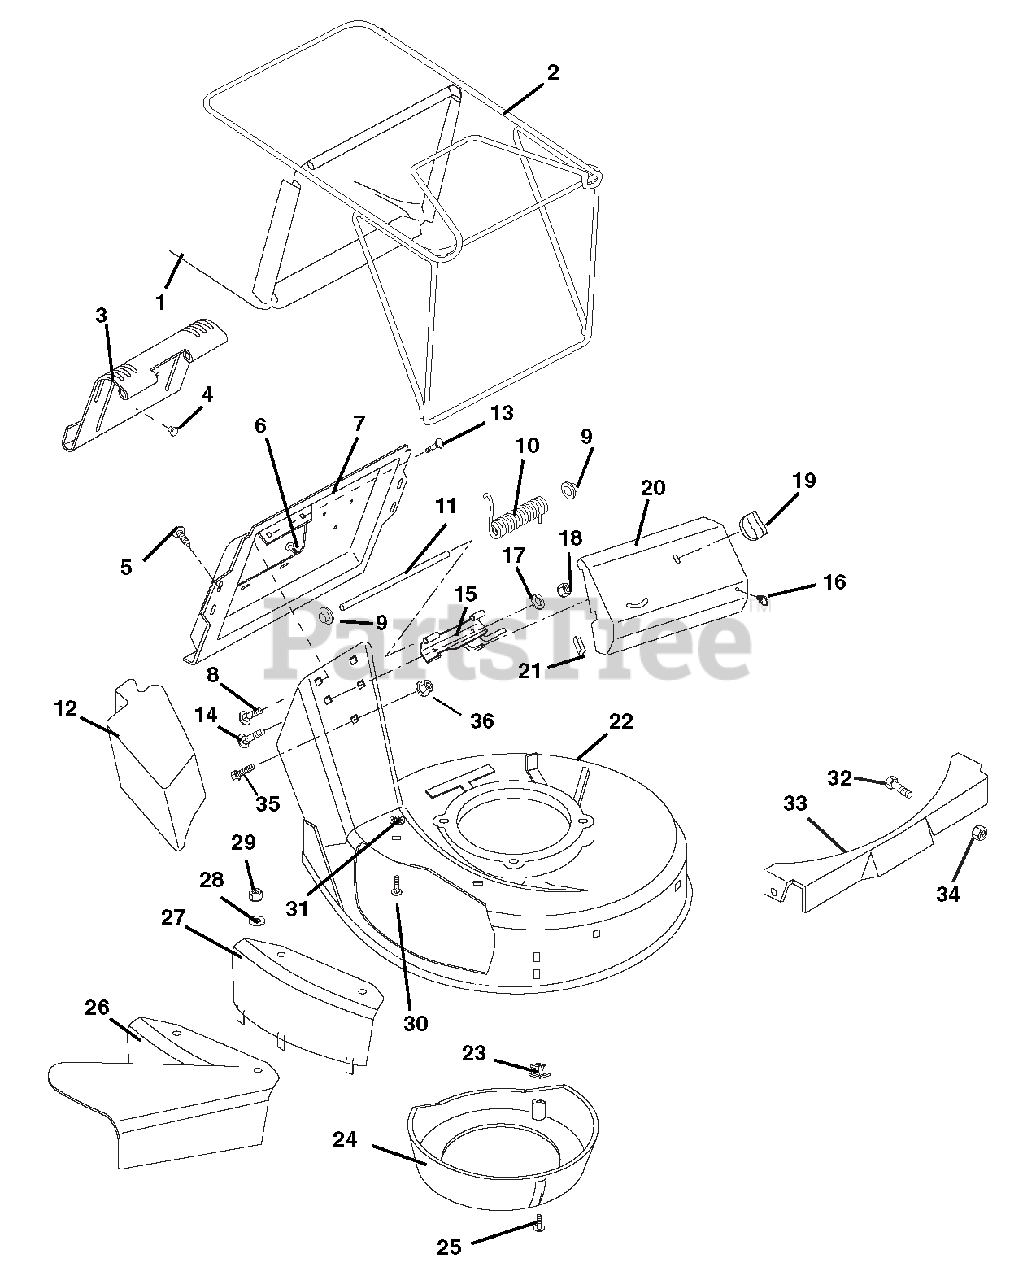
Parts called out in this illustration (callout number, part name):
1	BAG, CONSUMER BLACK 15 OZ/YD2
2	FRAME, WBLM BAGGER
3	CATCHER PLATE DOOR
4	BUTTON BUMPER
5	@SCR-TAP 12-24X.50 HWH TR YWZC
6	SCR-TAP 10-24X.375 TORX PHD YZ
7	CATCHER PLATE
8	@BLT-RHDSSQNK .25-20X.38 G2YZ
9	PUSH NUT, .25
10	SG-TORS .120X.68X3.09
11	DOOR PIN
12	MULCH MASTER MULCHER ACCESSORY
13	@NUT-SPNLK-FLG .25-20 YWZC
14	@BLT-RDHDSQNK .25-20X.75 G5YZ
15	HINGE BASE WELDEMENT
16	SNAP-IN CLIP
17	WSHR-LK .250X.077 HVY YWZC
18	@NUT-HEX .25-20 YWZC
19	WING - NUT
20	COVER, DRIVE
20	COVER, LM DRIVE
21	TRIM BUMPER
22	MOWER PAN HEAD W/SFTYDECALS SP
23	PLASTIC GROMMET
24	CENTER BAFFLE
25	SCR-TAP 10-16X.62 SLPH AB YWZC
26	SIDE DISCHARGE ASSEMBLY
27	COVER, SIDE DISCHARGE
28	@WSHR-FL-STL.406X.812X.065 YWZ
29	@NUT-LK-NYL .312-18 YWZC
30	BLT-RDHDSQSHK.31-18X.75 GR2 YW
31	NUT-PUSH .312
32	@BLT-RDHDSQNK .31-18X.50 G5YZ
33	PANEL-FRONT
34	@NUT-LK-TOP-FLG .31-18 YWZC
35	@BLT-HEX .38-16X.50 GR5 YWZC
36	@NUT-SPNLK-FLG .375-16 YWZC
